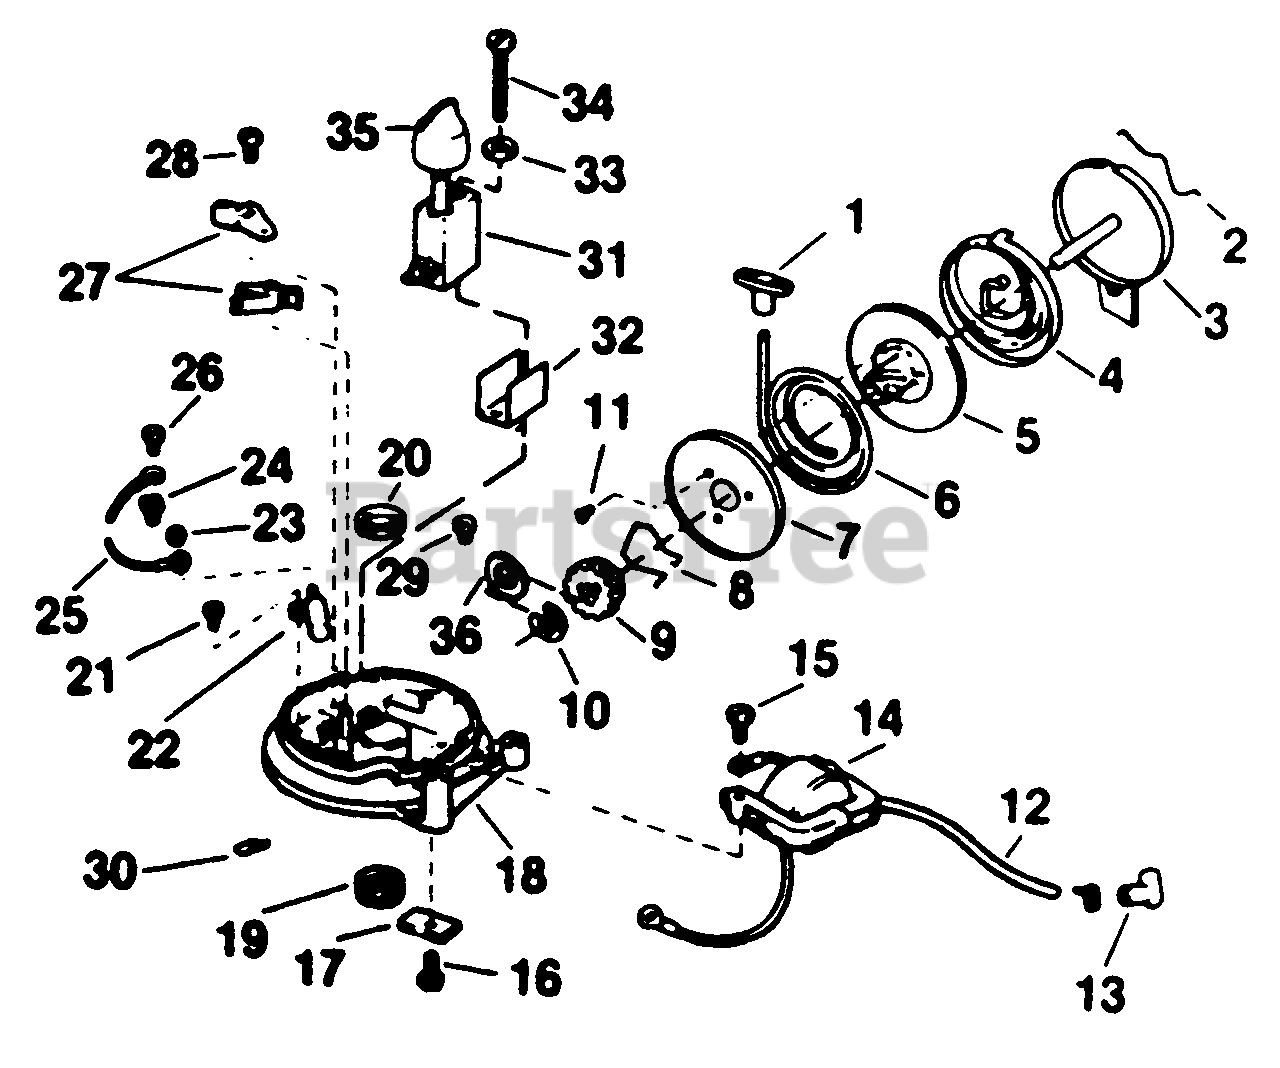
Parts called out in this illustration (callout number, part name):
1	Handle-Starter
2	Spring-Starter Rope Retainer
3	Spring-Cup-Pin Assembly
4	Spring-Starter
5	Pulley-Starter
6	Rope-Starter
7	Plate-Starter Pulley
8	Spring-Starter Pinion
9	Pinion-Starter
10	Retainer-Push-On
11	Screw-Threaded Cutting Starter
12	High Tension Lead Assembly
13	Cover & Terminal Assembly
14	Coil & Lamination Assy.
15	Screw-Lamination Mounting
16	SCrew-Starter Attach.
17	Clamp-Starter Pin
18	Arm. Plate Bearing & Oil Seal Assy.
19	Bearing
20	Oil Seal
21	Screw-Cond. Mtg.
22	Cond. & Nut Assy.
24	Grommet-Nylon
25	Terminal & Lead Assy.
26	Screw-Shut-Off Switch
27	Bracket Base & Arm Assembly
28	Screw-Breaker Base
29	Grommet
31	Shorting Switch
32	Insulator
